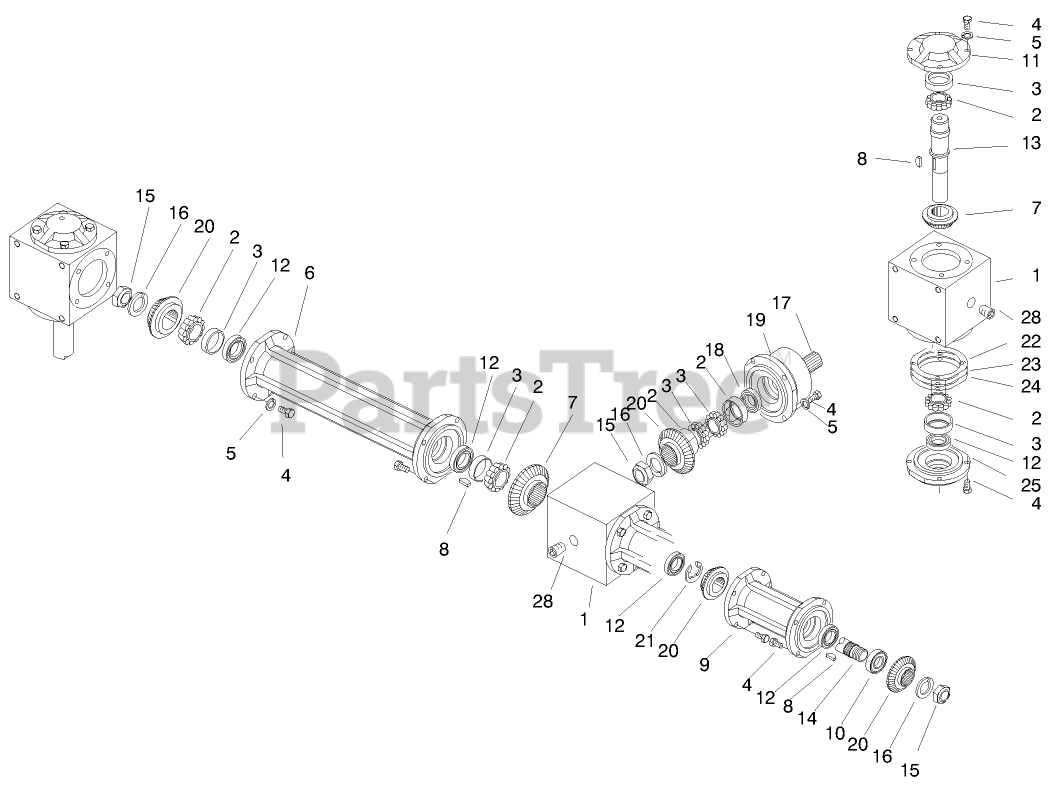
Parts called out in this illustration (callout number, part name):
1	HOUSING
2	BEARING - CONE
3	Cup
4	SCREW - HH
5	WASHER - LOCK
6	Connector-Hub
7	Gear-RH
9	Connector-Hub
10	BEARING - BALL
11	CAP - BLANK
12	Seal
13	Shaft-Thru
14	SHAFT
15	NUT - LOCK
16	WASHER - LOCK
17	SHAFT - HUB
20	PINION - LH
21	RING - RETAINING
22	Gasket-.015
23	Gasket-.005
24	GASKET - .003
25	CAP - THRU
26	I.d. Tag
27	I.d. Tag Cover
28	PLUG (OBS, C/R TO 281-10)
